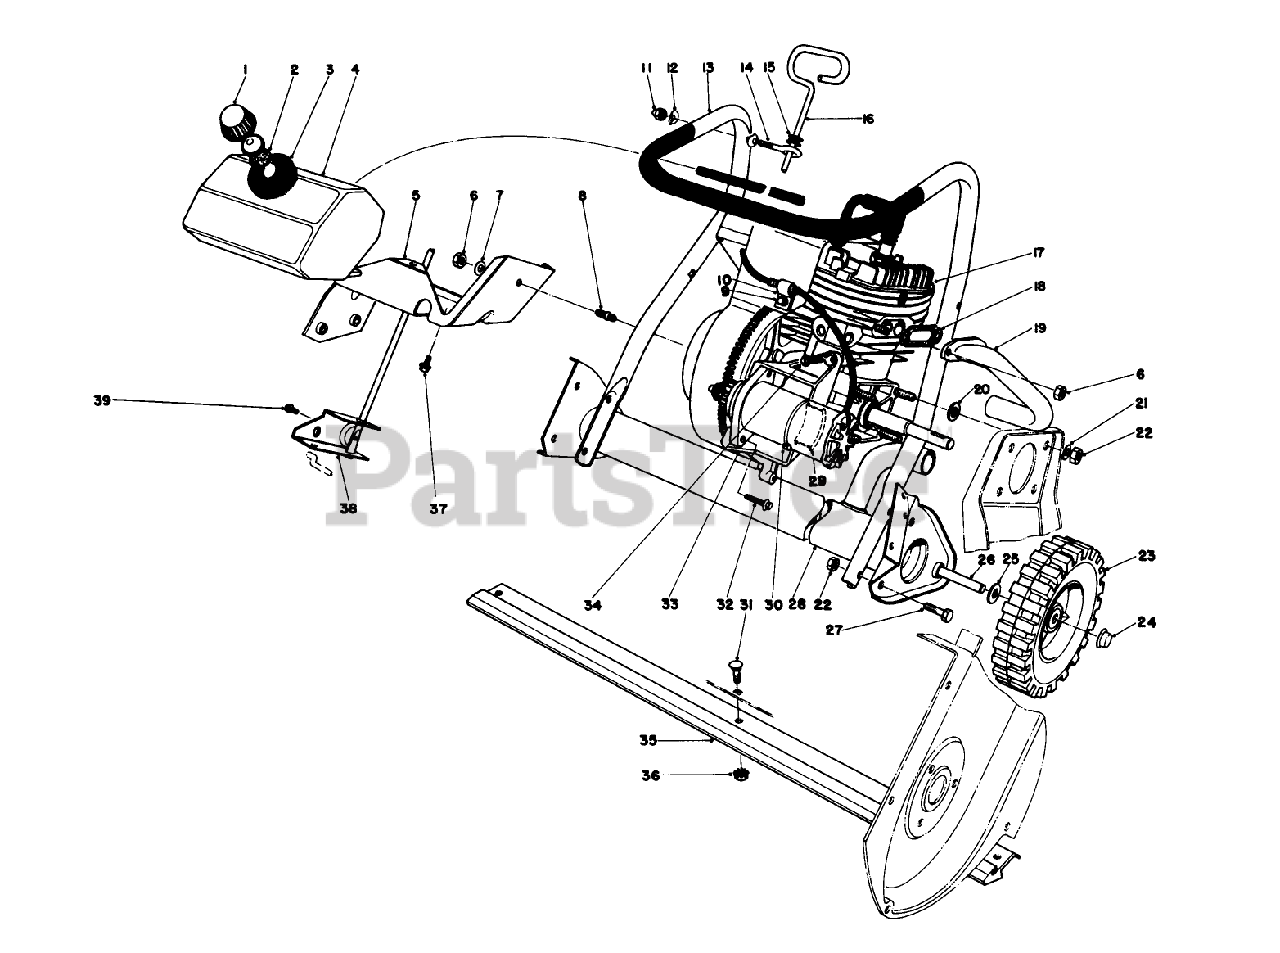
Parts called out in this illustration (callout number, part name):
1	GAS CAP ASM 32:1
2	GAS CAP GASKET
6	NUT-LOCK, CONE
9	SCREW-HWH
11	NUT-CAP
12	WASHER
17	Engine
20	WASHER-FLAT
21	WASHER-PLAIN
22	NUT-LOCK, NI
23	WHEEL
24	NUT-PUSH
25	WASHER-FLAT
27	SCREW-HH
28	EXHAUST MUFFLER ASM
30	TIE-CABLE
31	BOLT-CARR
32	SCREW-FLOW, TAPTITE
35	SCRAPER
36	NUT-KEPS
37	SCREW
39	SCREW
